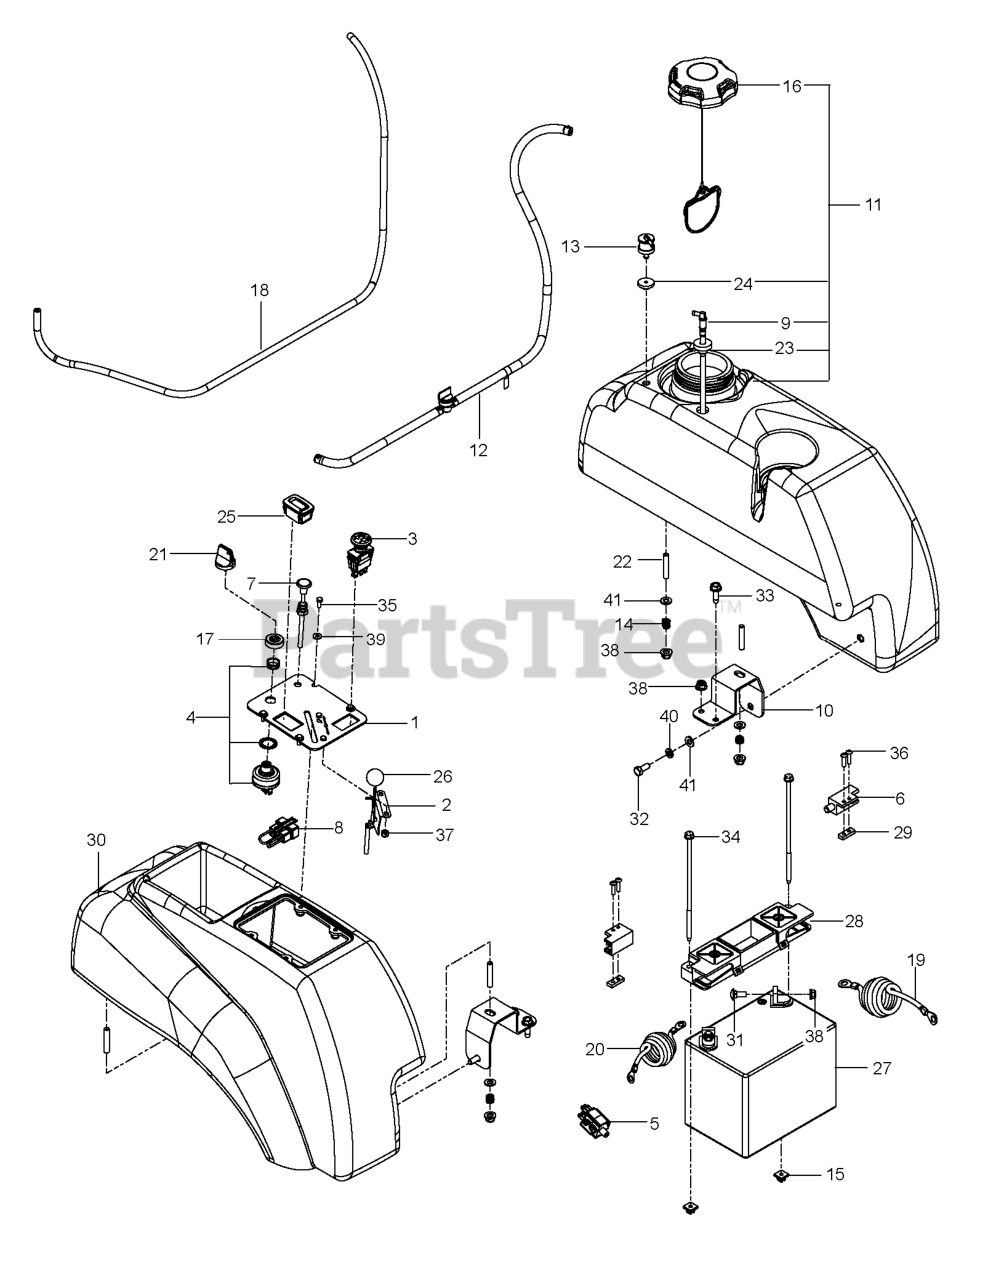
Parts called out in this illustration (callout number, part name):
1	PLATE.CONSOLE.BLACK
2	THROTTLE CABLE
3	RP SWITCH.PTO.TERMINAL.STD.RED
4	SWITCH, IGNITION, INDAK
5	SWITCH, BRAKE 3P
6	SWITCH INTERLOCKT
7	CHOKE CABLE
8	PLUG, TIMER
9	FITTING, FUEL
10	SUPPORT, TANK, BLK
11	ASSEMBLY, LT TANK, EPA GRAY
12	FUEL LINE ASM
13	VALVE.FUEL.CHECK
15	PUSH NUT-NYLON
16	CAP, FUEL
17	CAP IGNITION NUT
18	HOSE, VAPOR 3/16 X 48"
19	NEG. CABLE, 28"
20	POST.CABLE LONG
21	KEY, IGNITION
22	STUD, 5/16C
23	RUBBER GROMMET
24	GROMMET, CHECK VALVE
25	HOUR METER
26	KNOB.ROUND.BALL.BLACK
27	BATTERY, 12 V 330 AMP
28	BATTERY HOLD DOWN
29	TAPPED PLATE
30	FENDER CONSOLE
31	BOLT 5/16C X 3/4" CARRIAGE
32	HCS 5/16C X 3/4
33	RP BLT 5/16-18 X 1 THRD FORM D
34	BOLT - 1/4-20 X 7.5
35	HCS #10-24 X 1/2
36	SCR #10-24 X .75 SKT HD BLK
37	NUT 10-24 NYLOC
38	5/16-18 NYLOC FLANGE NUT
39	WASHER #10
40	WASHER.LOCK.HVY.HLCL.SPR.5/16
41	FLAT WASHER 5/16 SAE
